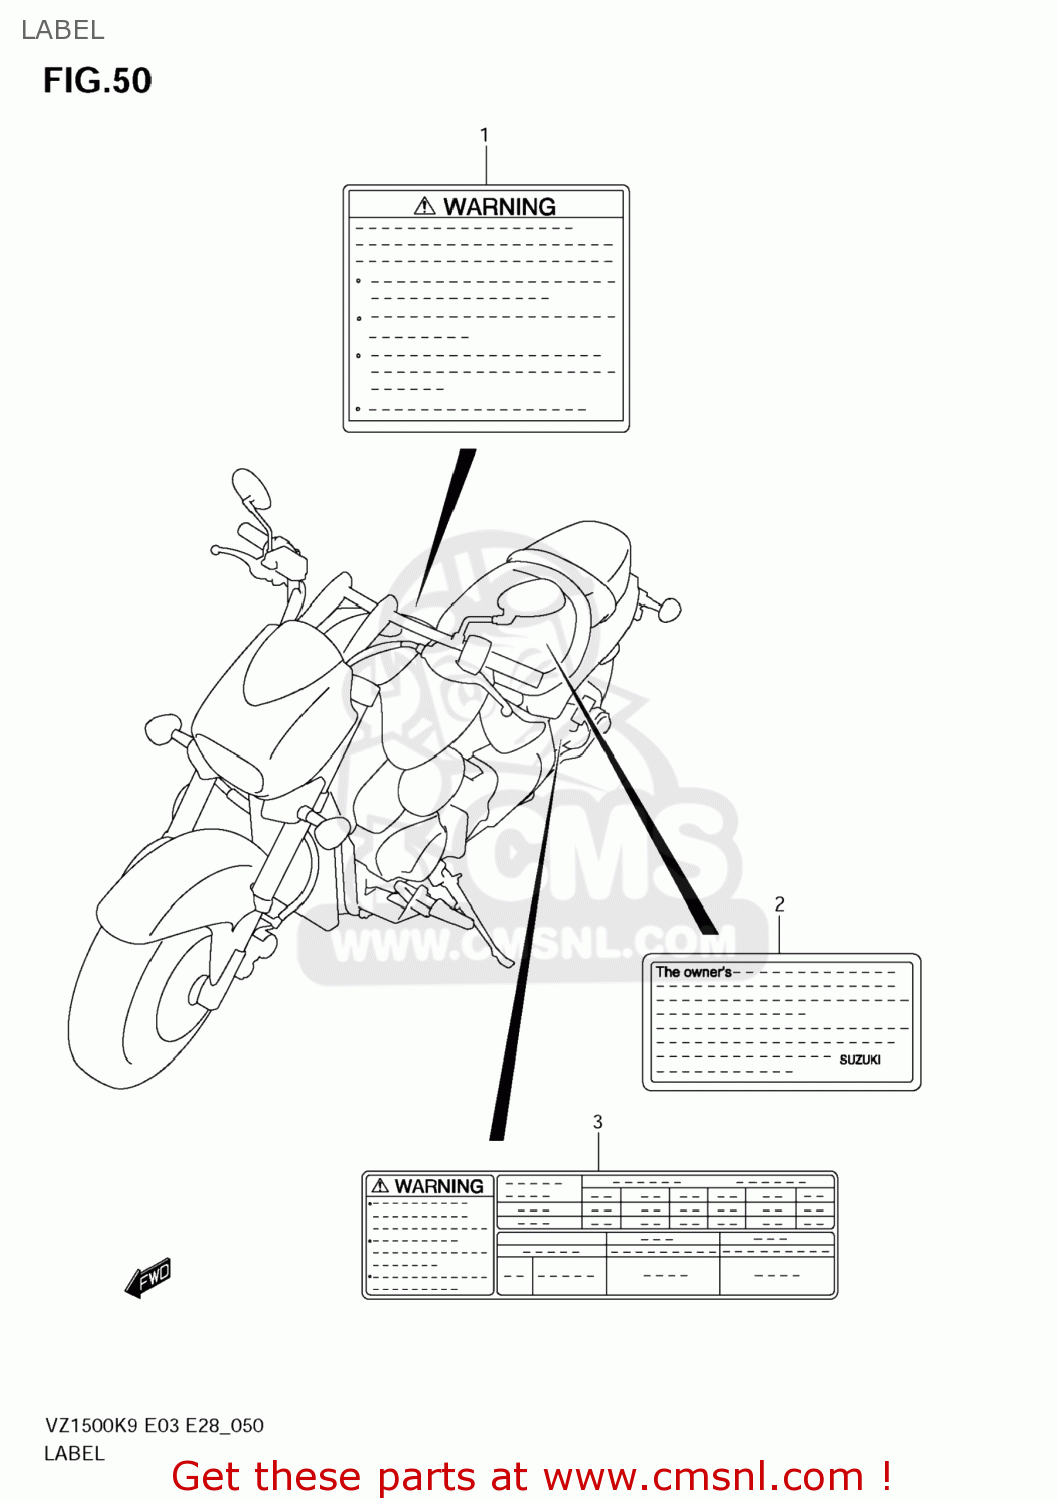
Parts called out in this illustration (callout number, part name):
1	LABEL,GENERAL WARNING
2	LABEL,MANUAL NOTICE
3	LABEL,TIRE INFORMATION
4	MANUAL,OWNER'S
